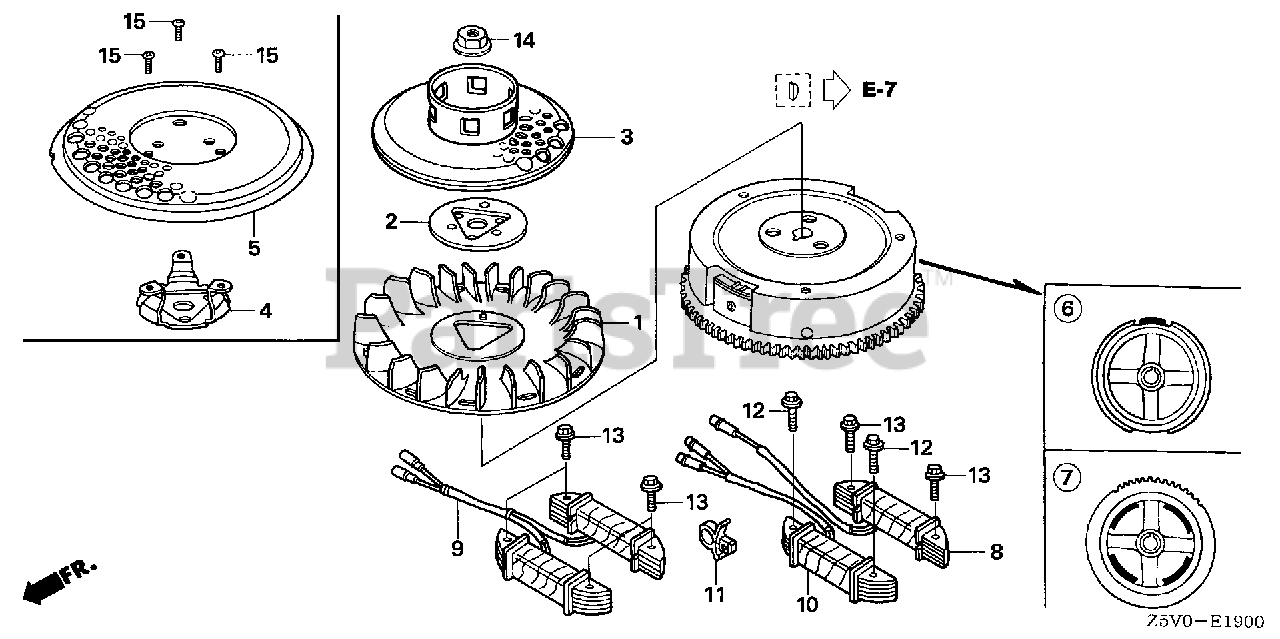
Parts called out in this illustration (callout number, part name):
1	FAN, COOLING
3	PULLEY, STARTER (SCREEN GRID)
7	FLYWHEEL (SEL-4POLE)
10	COIL ASSY., CHARGE (4A)
11	CLIP, BRAKE PIPE (A)
12	BOLT, FLANGE (6X28) (CT200)
14	NUT, SPECIAL (16MM)
